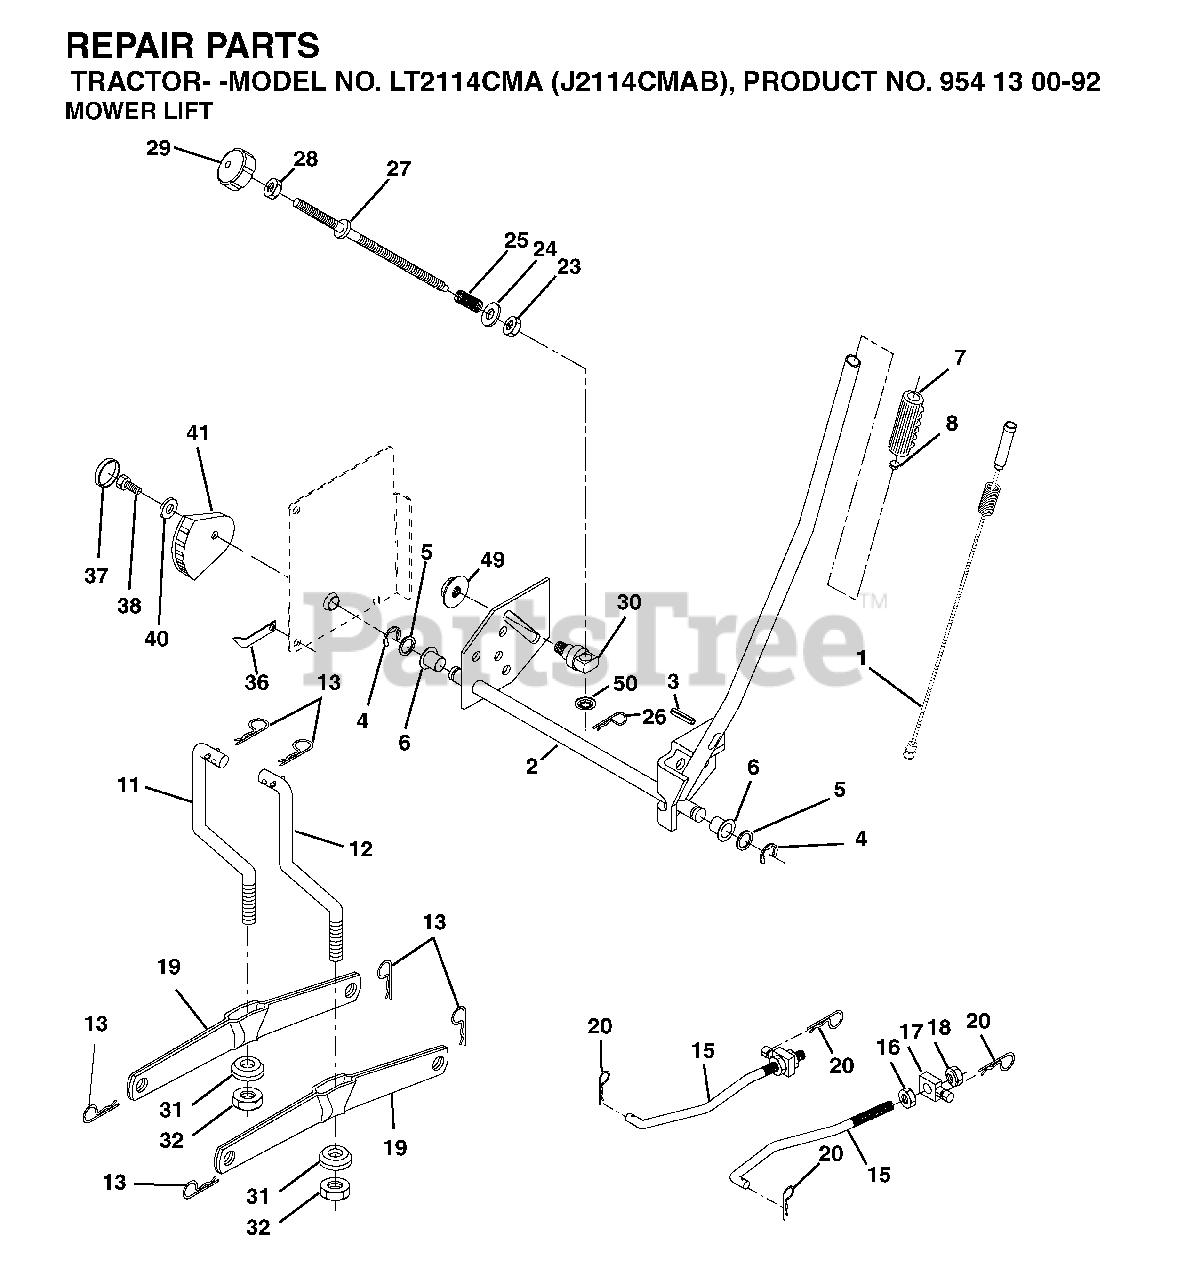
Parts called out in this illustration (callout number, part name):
1	WIRE ASM INNER W/ PLUNGER LT
2	SHAFT ASM R HANDLE
3	PIN GROOVE
4	RETAINING RING LT
6	BEARING.NYLON
7	GRIP HANDLE
8	PLUNGER BUT KIT
11	LINK
12	LINK
13	RETAINER-SPRNG RB
15	LINK.SUSPENSION.FRONT
16	NUT
18	NUT
19	ARM.REAR.SUSPENSION
20	SPRING RETAINER
25	SPRING**
26	RETAINER CLIP
27	ROD ADJ LIFT
28	NUT
29	KNOB INF 3/8-16
31	BEARING.PIVOT.LIFT
32	NUT CROWNLOCK 3/8-24
36	POINTER, HEIGHT INDICATOR
37	PLUG,HOLE
38	SCREW 5/16-18X1
41	HEIGHT INDICATOR
49	NUT
50	NUT PUSH M
